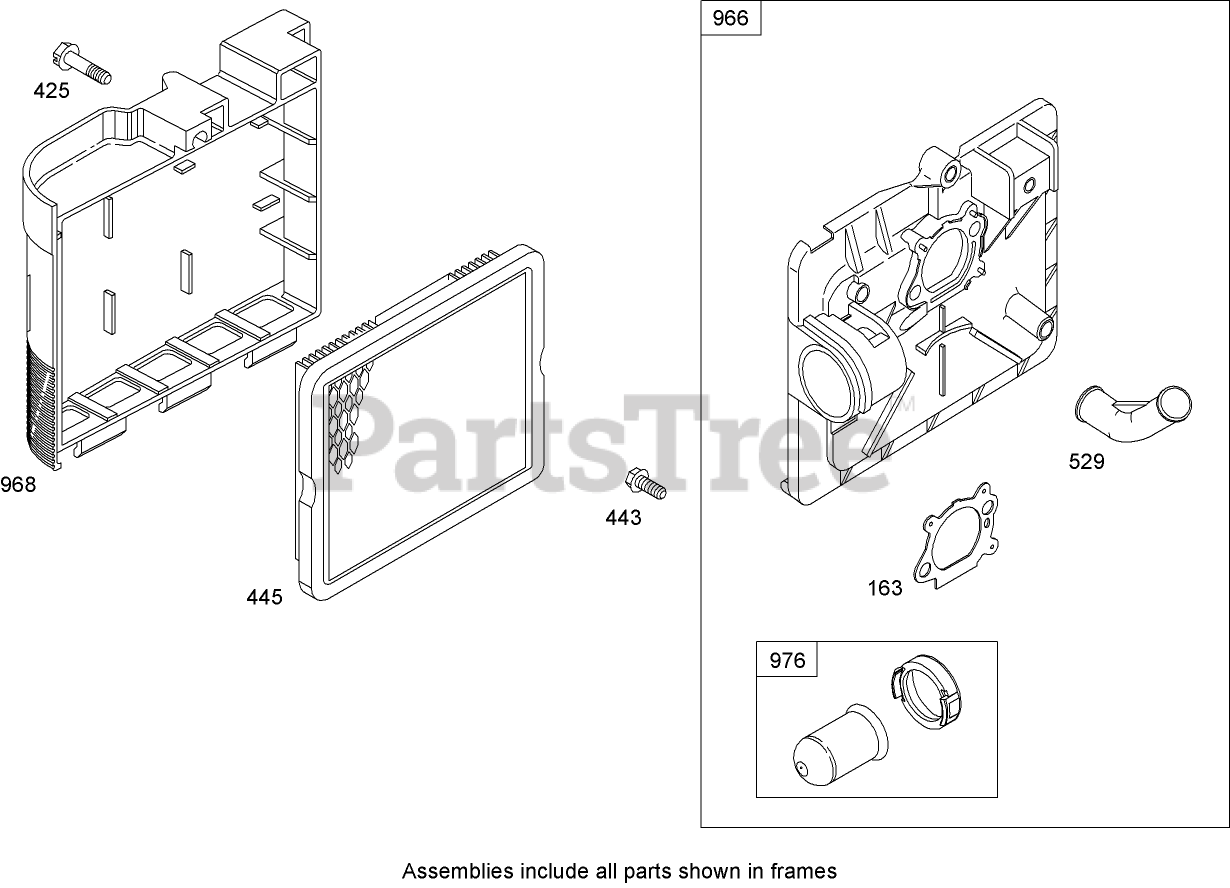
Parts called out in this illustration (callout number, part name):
163	Gasket-Cleaner, Air
425	Screw
443	Screw
445	Filter-Cartridge, Air Cleaner
529	Grommet
966	Pin-Roll
968	Cover-Cleaner, Air
976	Primer-Carburetor
